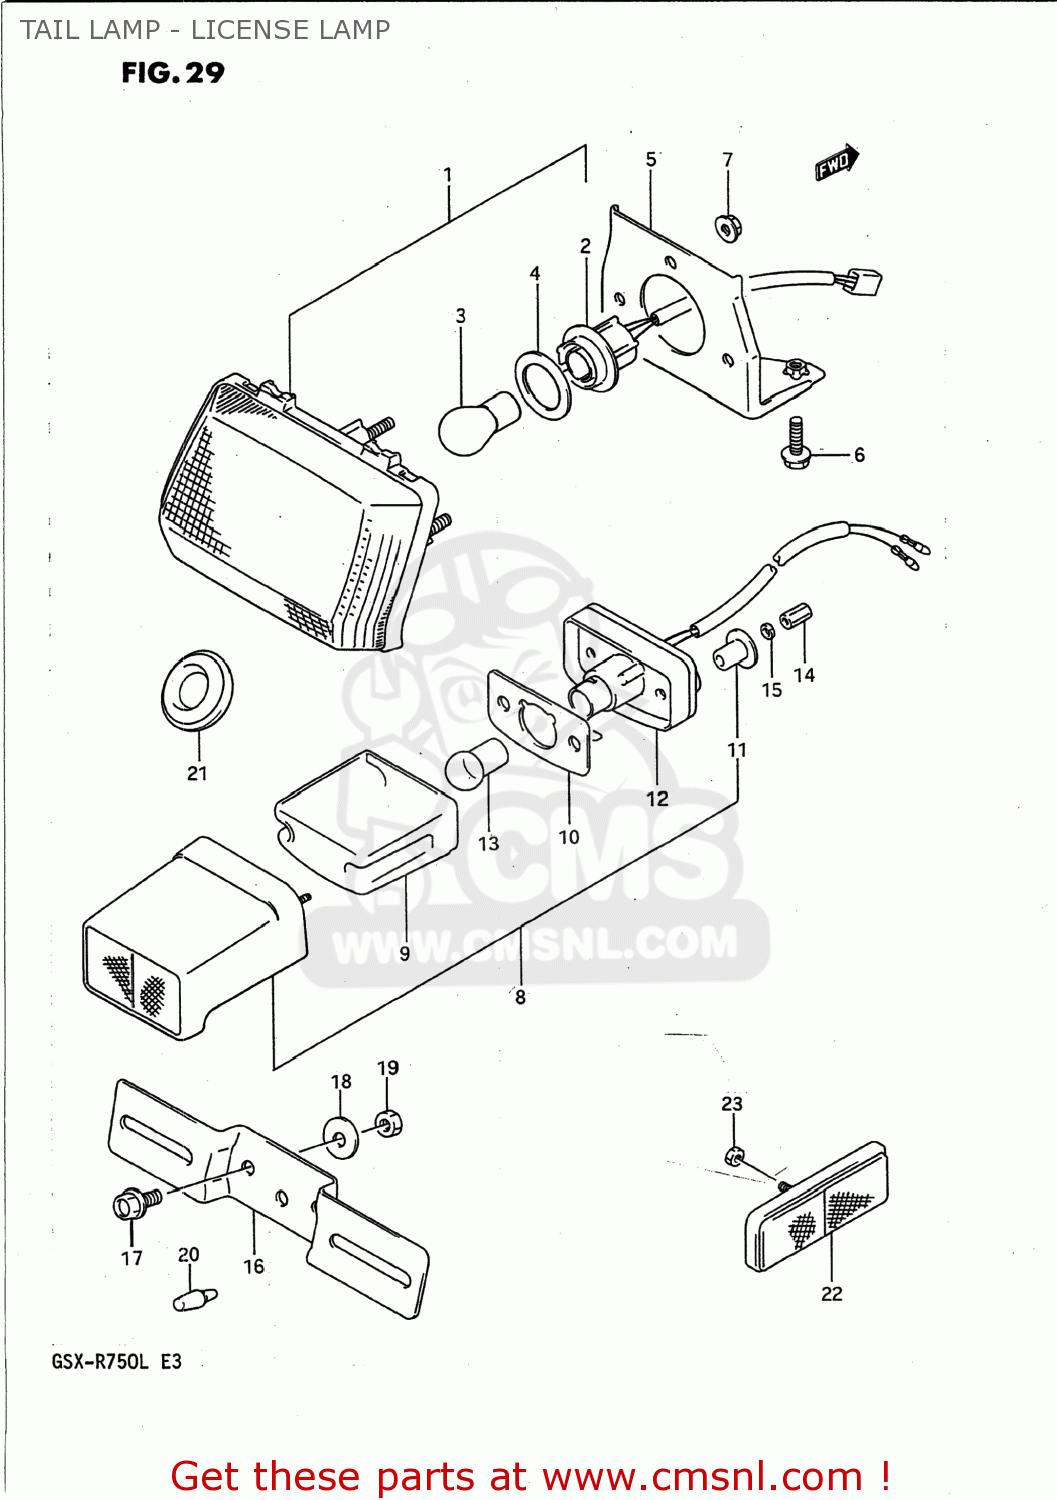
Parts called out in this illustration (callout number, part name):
1	LAMP ASSEMBLY,REAR COMBINATION
2	SOCKET
3	BULB(12V21/5W,BF141-49642A)
4	CUSHION,RUBBER
5	BRACKET COMP,REAR COMBINATION LAMP
6	BOLT
7	NUT
8	LAMP ASSEMBLY,LICENSE
9	LENS
10	GASKET,LICENSE LAMP (NAS)
11	SPACER
12	HOUSING,LICENSE
13	BULB
14	NUT
15	LOCK WASHER
16	BRACKET,LICENSE PLATE
17	BOLT
18	WASHER
19	NUT
20	CUSHION
21	CAP OD:40
22	REFLECTOR ASSEMBLY,REAR
23	NUT 5MM
